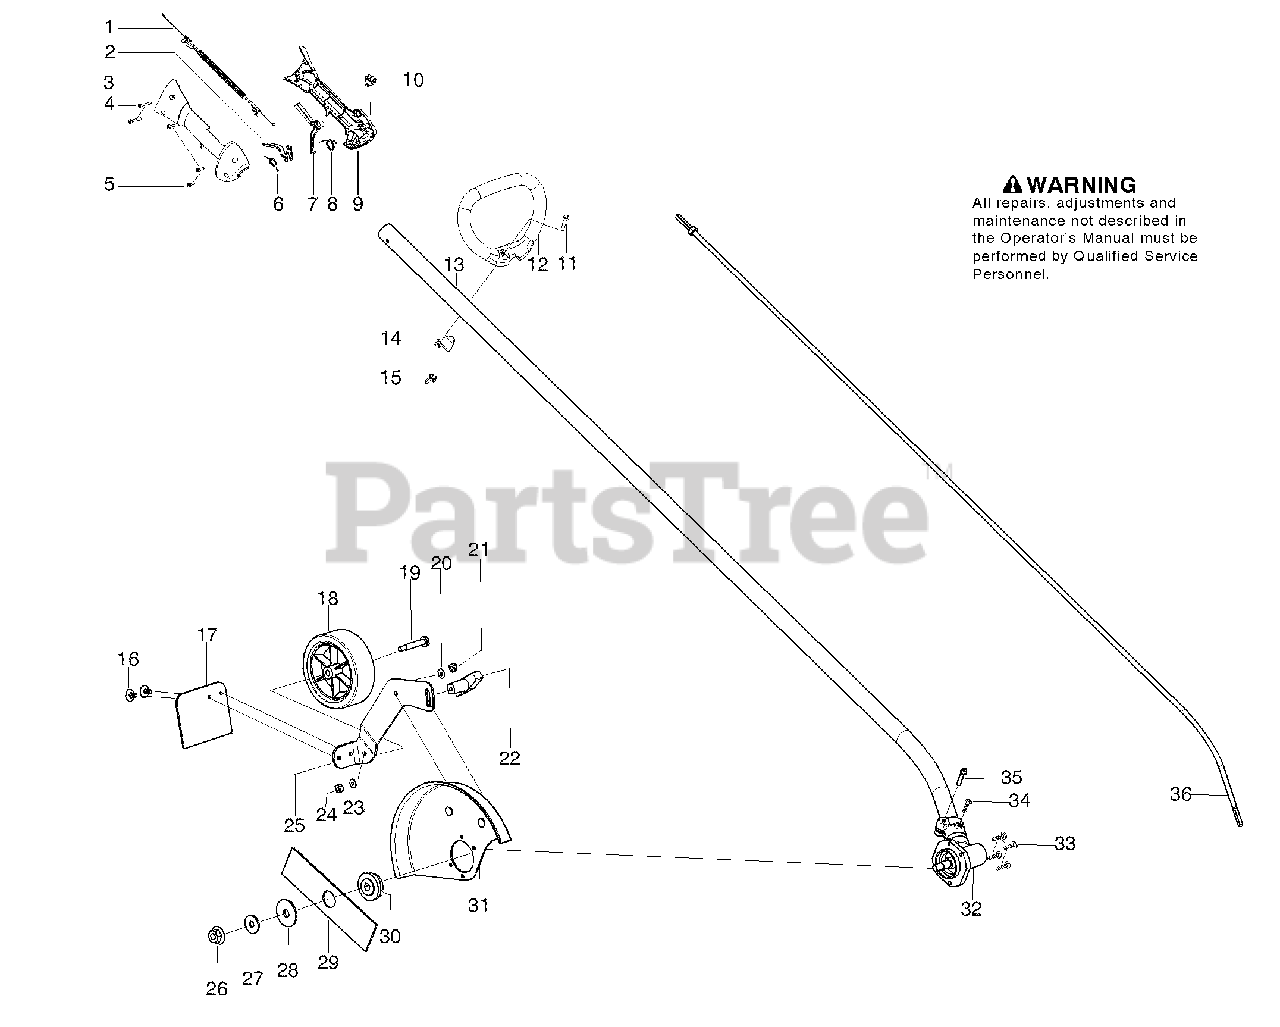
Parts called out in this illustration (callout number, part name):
1	Assy-Cable/Wire Harness
3	Housing-Throttle
6	Spring-Trigger
7	Lockout-Throttle
8	Spring-Lockout
9	Housing-Throttle
10	Kit-Switch
12	Handle-Assist
13	Kit-Driveshaft Edger
14	Clamp-Handle
15	Wingnut
16	Fastener - Mud Flap
17	Kit-Mud Flap
18	Wheel - 4"
19	Bolt-Shoulder Axle
25	Bracket-Wheel Adjustment
26	Nut-Flange L.H.
27	Washer-Belleville Spring
28	Washer-Flat
31	Kit-Edger Guard
32	Kit-Edger Gearbox
34	Screw
36	Flexshaft
